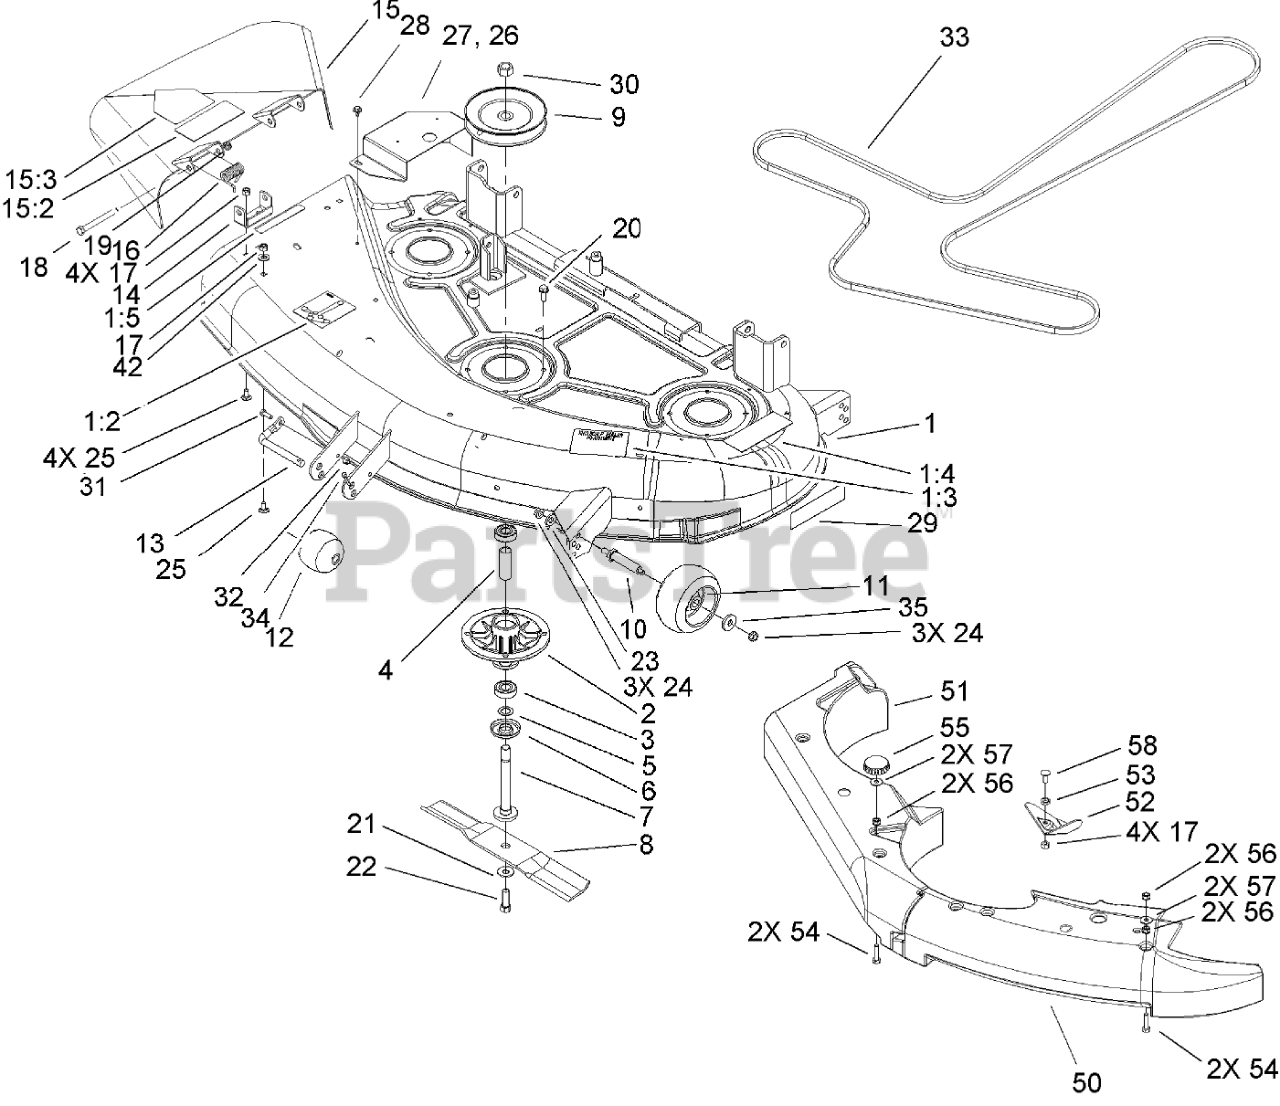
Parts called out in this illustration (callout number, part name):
1	44 INCH DECK ASM
1:2	DECAL-ROUTING, BELT
1:3	DECAL-ANTI SCALP
1:4	DECAL-DANGER
1:5	DECAL-DANGER
2	HOUSING-SPINDLE
3	BEARING-BALL
4	SPACER
5	SPACER
6	SHIELD-BEARING
7	SHAFT-SPINDLE
8	BLADE-RECYCLER
9	Pulley ASM
10	SPACER
11	WHEEL-GAGE
12	ROLLER
13	Shaft-Roller
14	BRACKET-PIVOT
15	DEFLECTOR ASM
15:2	DECAL-DANGER
15:3	DECAL-DANGER
16	SPRING
17	NUT-LOCK, NI
18	SCREW-HH
19	NUT-HEX
20	SCREW-TAPTITE
21	WASHER-BELLEVILLE
22	SCREW-HH
23	WASHER-BELLEVILLE
24	NUT-HHF, WHIZ
25	SCREW-CARR
26	Cover-Belt, LH
27	Cover-Belt, RH
28	SCREW-HHFTF
30	NUT-HEX
31	SCREW-HH
32	NUT-LOCK, NI
33	BELT V
34	PIN-COTTER
35	WASHER
42	WASHER-FLAT
50	BAFFLE-LH
51	BAFFLE-RH
52	PLATE-KICKER
53	SPACER
54	SCREW-HH
56	NUT-KEPS
57	WASHER-BELLEVILLE
58	SCREW-CARR
